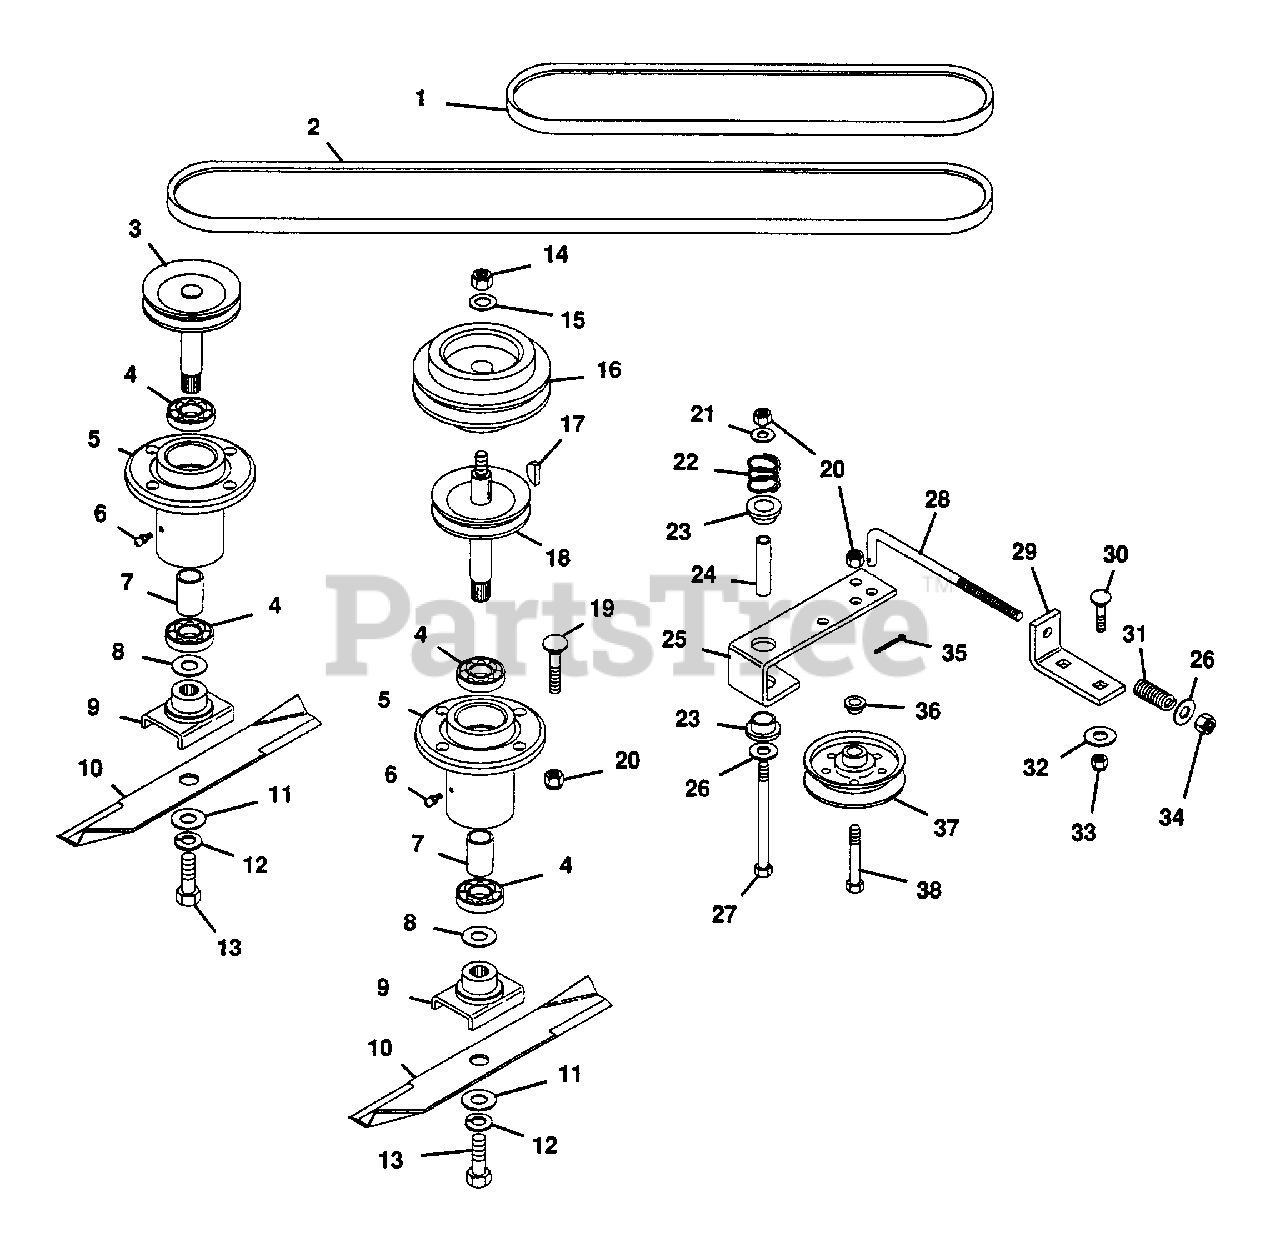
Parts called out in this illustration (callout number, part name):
1	Belt, Mower Drive
2	Belt, Mower
3	Weldment, Spindle
4	Bearing, Ball .984x2.047x.590
5	Housing, Spindle
6	Fitting, Lube 1/8
7	Bush., St. 1.00x1.25x1.58 Stl.
8	Washer, Flat .975x1.970x.030
9	Weldment, Blade Cradle
10	Blade
11	Wshr, Flat .687x1.312x.122/.146
12	Washer, Lock 5/8 SP
13	Bolt, Hex 5/8-11x1.25
14	Nut, Lock 5/8-11
15	Washer, Flat .656x1.312x.095
16	Sheave, Driven
17	Key, Woodruff .250x.75 Hard
18	Weldment, Driver Shaft
19	Bolt, 3/8-16x1.50 Rd Hd Sq Nk
20	Nut, Lock 3/8-16
21	Washer, Flat .438x1.000x.083
22	Spring, Comp. 1x.80x36Lb/In
23	Bush., Flg. .764x1.47x.560 Ny.
24	Bush., St. .437x.750x2.44 Stl.
25	Arm, Idler Pivot
26	Washer, Flat .406x.812x.065
27	Bolt, Hex 3/8-16x3.75
28	Rod, Idler
29	Bracket, Idler Rod
30	Bolt, Carriage 5/16-18x1.00
31	Spring, Comp. 1x.78x338 Lb/In
32	Washer, Flat .344x.688x.065
33	Nut, Lock 5/16-18
34	Nut, Lock 3/8-24
35	Pin, Cotter 3/32x1.00
36	Bush., St. .406x.750x.188 Stl.
37	Sheave, Idler
38	Bolt, Hex 3/8-16x2.25
